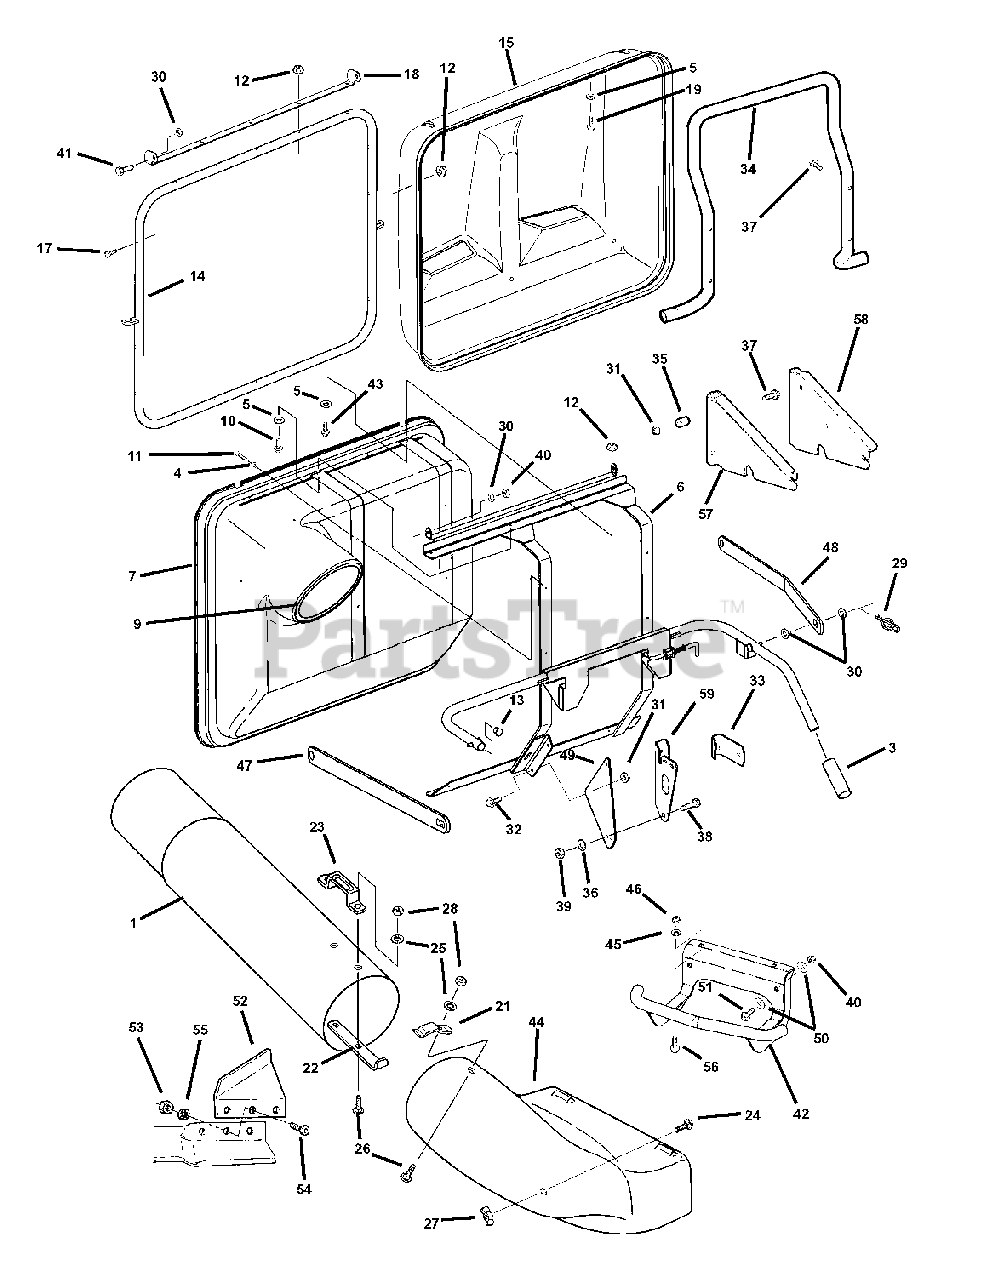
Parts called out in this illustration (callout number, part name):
1	TUBE, Grass
3	GRIP
4	WASHER, 11/32 Flat
5	WASHER, 3/16 Flat
6	WELDMENT, Front Cover Brace
7	COVER, Front
9	GASKET, Chute
10	SCREW, #10-24 x 1/2" Hex Washer Self-Tap (Torx)
11	SCREW, 1/4-20 x 5/8" Pan Head Self-Tapping
12	NUT, #10-24 Hex Fl. Lock
13	END CAP, Tube
14	WELDMENT, Rear Cover Brace
15	COVER, Rear
17	BOLT, #10-24 x 1-1/2" Oval Head
18	HINGE, Rear Cover
19	SCREW, #10-24 x 1-1/2 Machine
21	LATCH, Chute/Tube
22	BASE, Handle
23	HANDLE, Tube
24	BOLT, 5/16-18 x 1" Round Head Short Neck Carriage, Grade 5
25	WASHER, 1/4 Internal Tooth Lock
26	BOLT, 1/4-20 x 3/4" Round Hd. Short Nk. Carriage, Gr. 5
27	NUT, 5/16-18 Wing
28	NUT, 1/4-20 Hex
29	PIN, 3/8 Self Lock Cotter
30	WASHER, 3/8" Flat
31	NUT, 5/16-18 Flange Lock
32	BOLT, 5/16-18 x 5/8" Hex Flange Lock
33	SUPPORT, Bumper
34	BUMPER, Rear
35	SPACER, Bumper Bracket
36	WASHER, 1/2 Internal Tooth Lock
37	SCREW, 5/16-18 x 1-3/4" Hex Washer Self-Tapping
38	BOLT, 1/2-13 x 1" Hex Head Cap Grade 5
39	NUT, 1/2-13 Hex Gr. 5
40	NUT, 3/8-16 Hex Lock
41	SCREW, 3/8-16 x 1" Hex Head Cap, Grade 5
42	WELDMENT, LT Bumper
43	BOLT, #10-24 x 3/4" Hex Flange Lock, Grade 5
44	ASSEMBLY, Chute
45	WASHER, 5/16" Flat
46	NUT, 5/16-18 Hex Nyloc
47	LINK, Handle (Right Hand)
48	LINK, Handle (Left Hand)
49	PLATE, Hitch
50	WASHER, 7/16" Flat
51	BOLT, 3/8-16 x 1" Hex Flange Lock
52	Air Lift
53	NUT, 5/16-24 Hex
54	SCREW, 5/16-24 x 5/8" Oval Head Machine
55	WASHER, 5/16 Internal Tooth Lock
56	BOLT, 5/16-18 x 7/8" Hex Flange Lock
57	BRACKET, Bumper Support (Right Hand)
58	BRACKET, Bumper Support (Left Hand)
59	BRACE, Bumper
